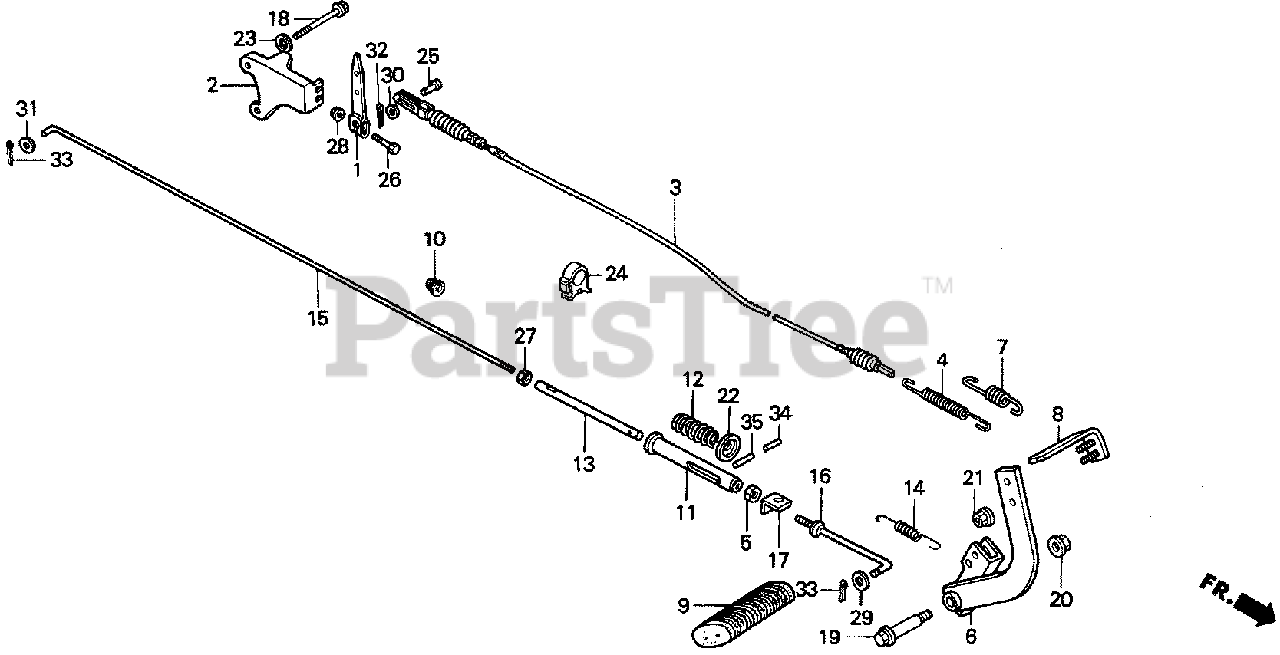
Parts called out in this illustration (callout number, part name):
1	ARM, CLUTCH
2	HOLDER, CLUTCH WIRE
3	CABLE B, CLUTCH (BRAKE)
4	SPRING, CLUTCH
5	NUT, HEX. (6MM) (LEFT HAND THREAD)
6	PEDAL, FOOT BRAKE
7	SPRING, BRAKE PEDAL
8	BRACKET, BRAKE PEDAL
9	RUBBER, BRAKE PEDAL
10	BUSH, BRAKE ROD
11	PIPE, BRAKE
12	SPRING, BRAKE ROD SETTING
13	SHAFT, SPRING SET
14	SPRING, BRAKE DAMPER
15	ROD A, FOOT BRAKE
16	ROD B, FOOT BRAKE
17	PLATE, DAMPER SPRING SETTING
18	BOLT, FLANGE (6X65)
19	BOLT, P.T.O. CLUTCH LEVER
20	NUT, SELF-LOCK (8MM)
21	NUT, FLANGE (8MM) (NOT AVAILABLE)
22	WASHER, BRAKE SPRING SETTING
23	WASHER (6X15)
24	CLIP, CABLE (8MM)
25	PIN, CLUTCH JOINT
26	BOLT, HEX. (5X25)
27	NUT, HEX. (8MM)
28	NUT, FLANGE (5MM)
29	WASHER, PLAIN (5MM)
30	WASHER, PLAIN (6MM)
31	WASHER, PLAIN (8MM)
32	PIN, SPLIT (1.6X12)
33	PIN, SPLIT (2.0X15)
34	PIN, SPRING (3X28)
35	PIN, SPRING (5X28)
